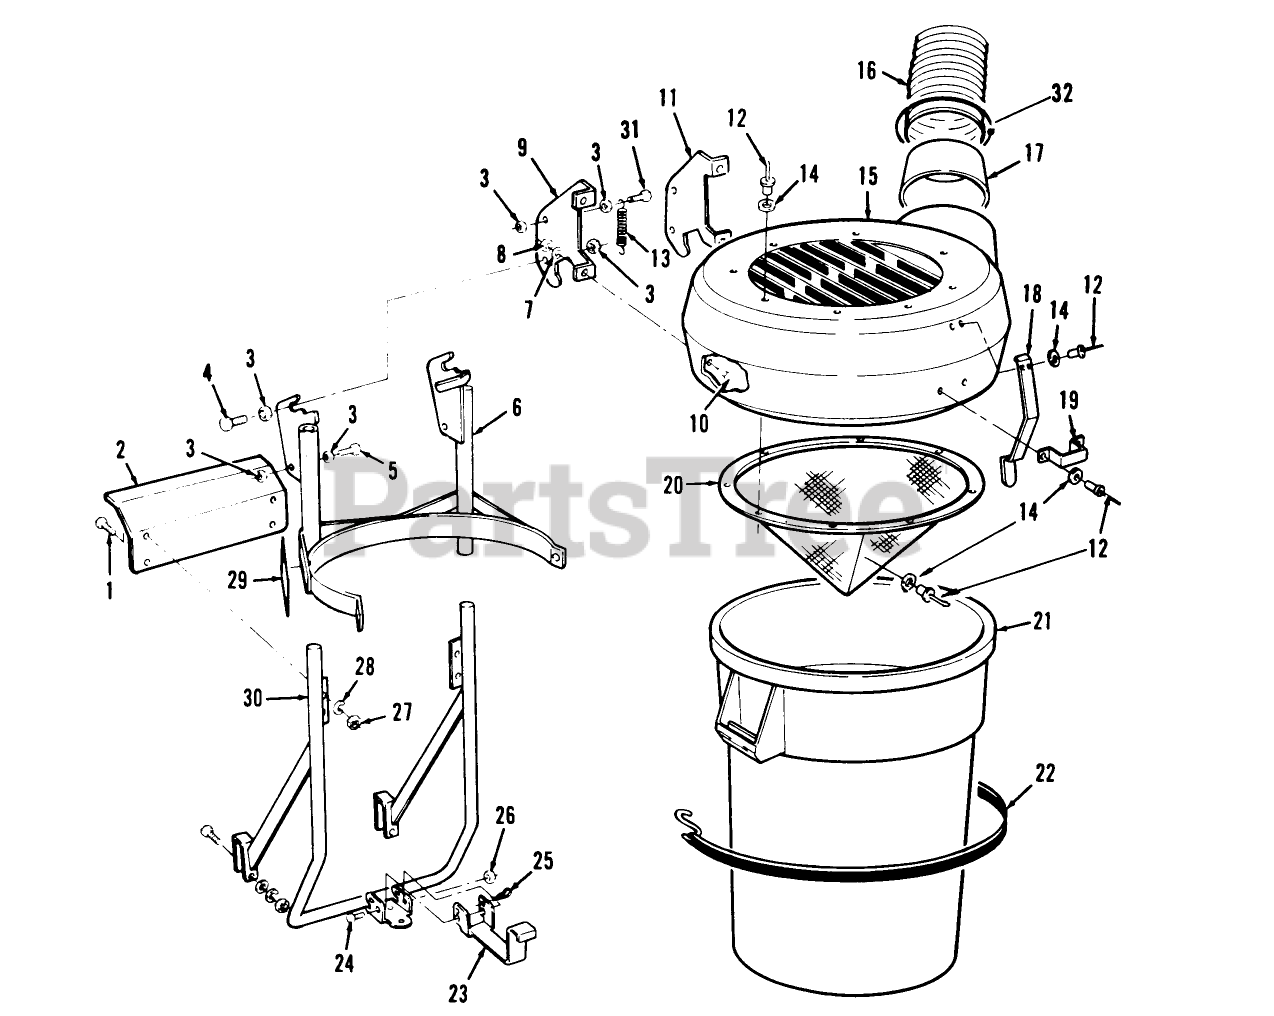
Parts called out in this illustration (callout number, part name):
1	SCREW-HH
2	SHIELD-HEAT *B
3	NUT-HEX
4	SCREW-HH
5	SCREW-HH
7	WASHER-PLAIN
8	NUT-LOCK, NI
9	LH TOP BRACKET *B
10	SCREW-HH
12	RIVET-POP
13	SPRING-EXTENSION
15	TOP-CANISTER
17	SEAL ASSEMBLY *NP
19	BRACKET *B
22	STRAP *B
23	BRACKET-SUPT *B
24	Screw-Cap Hex. Hd.
25	Hairpin
26	NUT-LOCK, NI
27	NUT-LOCK, NI
28	WASHER-PLAIN
29	DECAL-DANGER
30	MOUNT-BAGGER W.A. *B
31	SCREW-HH
